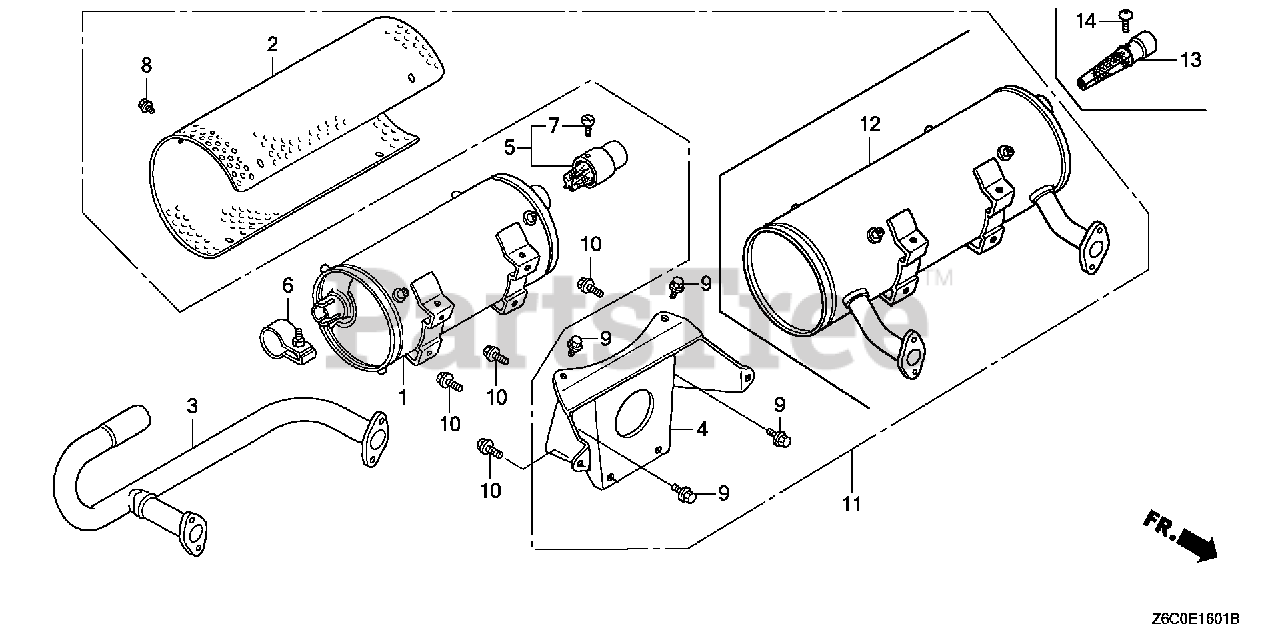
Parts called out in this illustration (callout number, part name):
1	MUFFLER (HIGH)(NELSON)(BLACK MUFFLER) (SHIFT18300-ZJ1-881) (IF N/A - #18300-ZJ1-891 LT.)
2	PROTECTOR, MUFFLER (HIGH) (FUTABA) (FOR BLACK MUFFLER)
2	PROTECTOR, MUFFLER (HIGH) (FUTABA) (FOR SILVER MUFFLER)
3	PIPE, EX. (HIGH-L) (FOR BLACK MUFFLER)
4	STAY, MUFFLER (HIGH-FUTABA) (FOR SILVER MUFFLER)
5	ARRESTER, SPARK (FOR BLACK MUFFLER)
6	BAND ASSY. (FOR BLACK MUFFLER) (NOT AVAILABLE)
7	SCREW (NELSON) (SCREW UNAVAILABLE SEPARATELY. ORDER DEFLECTOR KIT.)
8	BOLT, FLANGE (6X8)
9	BOLT, FLANGE (8X14)
10	BOLT, FLANGE (8X20) Use up to Engine SN 1609606.
11	MUFFLER ASSY. (HIGH-L) (FUTABA) (SILVER MUFFLER) (FOR SILVER MUFFLER)
12	MUFFLER COMP. (HIGH-L) (FUTABA) (SILVER MUFFLER) (FOR SILVER MUFFLER)
13	ARRESTER KIT (HIGH)
13	ARRESTER, SPARK (FOR SILVER MUFFLER)
14	SCREW, TAPPING (5X8) (FOR SILVER MUFFLER)
